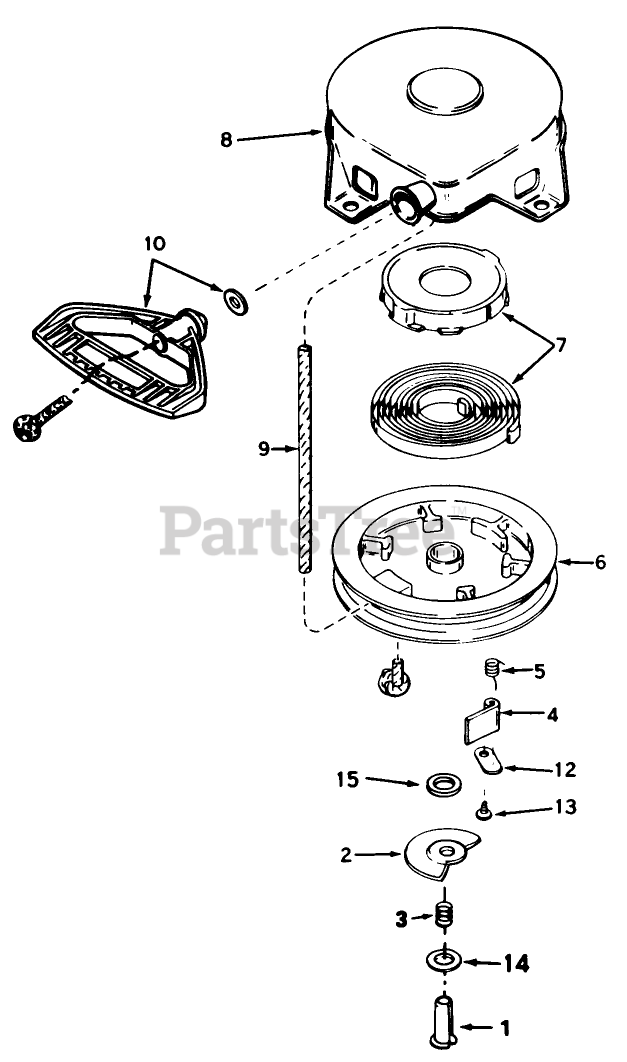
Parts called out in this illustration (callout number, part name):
1	Pin Spring
2	Washer
3	Brake Spring
4	Dog-Starter
5	Spring-Dog
6	Pulley
7	Spring Keeper Assy
8	Housing-Starter
9	Rope-Starter
10	Handle-Starter, Mitten Grip
12	Retainer-Dog
13	Screw
14	Washer
15	Washer
